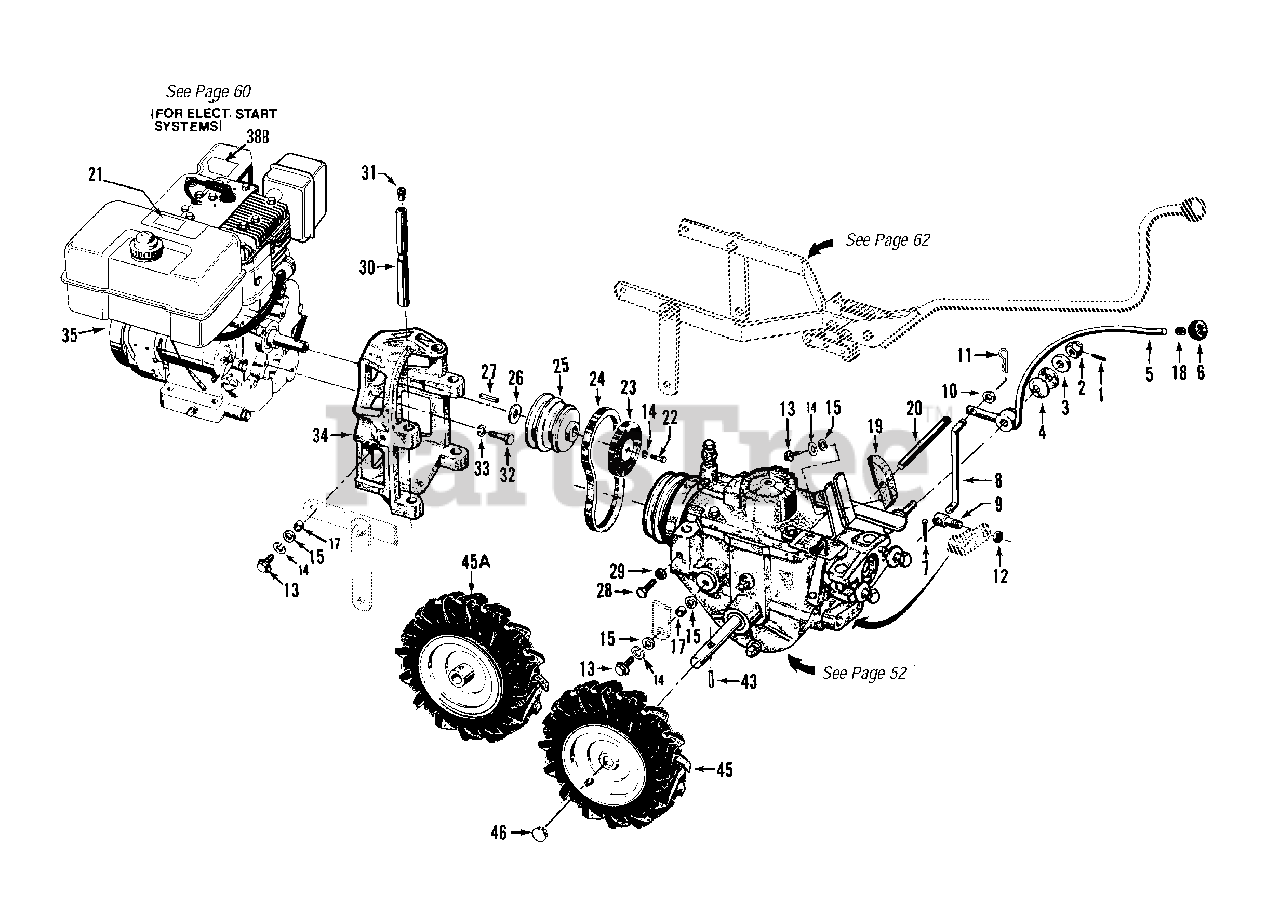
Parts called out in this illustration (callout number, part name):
1	Pin-spring, 1/8"
2	Nut-castle (slotted), 1/2"-20
3	Washer-shoulder, 1/2"
4	Washer-disc spring
5	Lever-wheel speed shift
6	Knob-wheel speed shift lever
7	Pin-cotter, 3/32" x 1"
8	Rod-connecting rod, wheel speed shift lever
9	Swivel-connecting rod
10	Washer-flat, 5/16", S.A.E.
11	Pin-hair cotter
12	Locknut-hex hd., 5/16"-18
13	Bolt-flanged hex hd., 3/8-16 x 1"
14	Lockwasher-spring lock, 3/8"
15	Washer-flat, 3/8", S.A.E.
17	Bushing-spacer, 19/64" (.300"lg.)
18	Ring-retaining (tolerance ring)
19	Block- belt adjustment, 3-7/8"
20	Rod- belt adjust., 7" with measuring gauge
21	Decal- engine stabilization
22	Bolt-hex hd., 3/8-24 x 1-1/2"
23	Disc-reverse
24	Belt-forward drive
25	Pulley-engine power take off
26	Shim-engine pulley, 1/16"
26	Shim-as above, 1/32"
27	Key-engine pulley, 3/16"sq. x 2-1/2"
28	Bolt-hex hd., 5/16-18 x 1", Grade 5
30	Bar-engine mounting
31	Plug-thread protector, red plastic
32	Bolt-hex hd., 5/16-24 x 1-1/8"
33	Lockwasher-spring lock, 5/16"
34	Mount- engine to tiller
35	8HP Briggs & Stratton Engine-Recoil or electric start.
35	10HP Briggs & Stratton Engine-Electric start
38B	Decal-hot surface safety warning
43	Pin- roll, 5/16" x 1-1/2"
45	Wheel & Tire Assy-bar tread, left side, 4:80 x 8" tubeless tire
45A	Wheel & Tire Assy-bar tread, right side.
46	Cap-wheel hub
